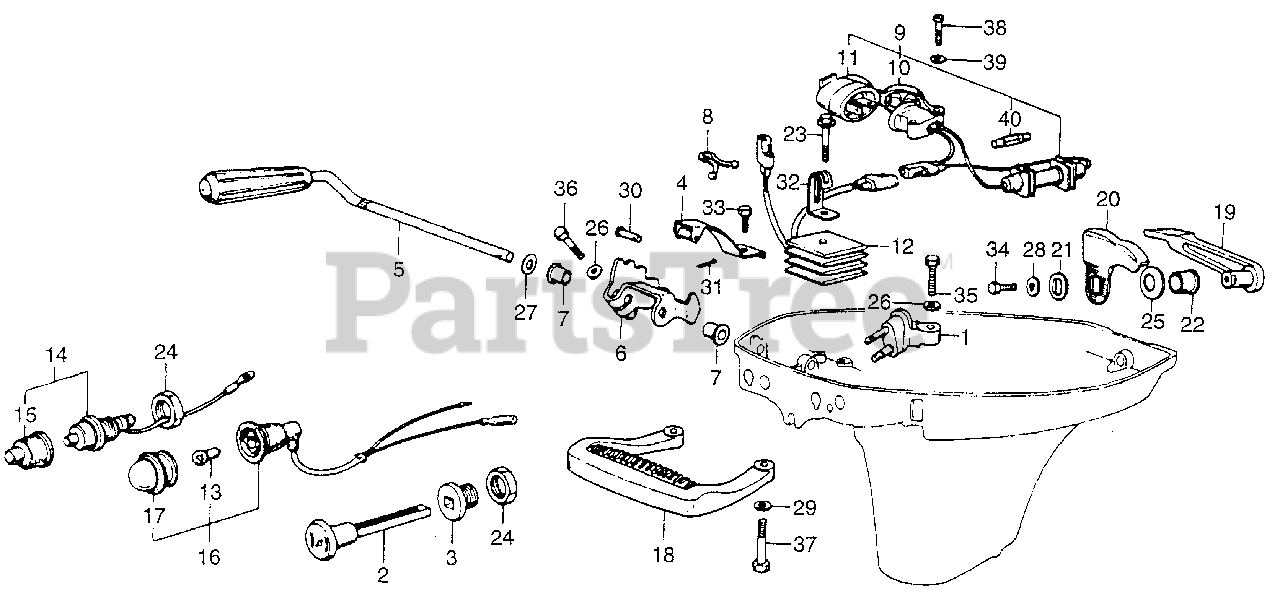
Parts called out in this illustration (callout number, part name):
1	CONNECTOR, FUEL *B9* (ATLANTIS BLUE) (NOT AVAILABLE)
2	KNOB, CHOKE
3	GUIDE, CHOKE KNOB
4	SPRING, CLICK
5	SHAFT, SHIFT
6	ARM, GEARSHIFT (NOT AVAILABLE)
7	BUSH, SHAFT
8	CLIP, PURSE LOCK (5MM)
9	RECEPTACLE ASSY., LAMP (NOT AVAILABLE)
10	RECEPTACLE (NOT AVAILABLE)
11	PLUG, RECEPTACLE
12	RECTIFIER ASSY.
13	BULB, DASH (12V3.4W) (IMASEN)
14	SWITCH, ENGINE
15	CAP, BUTTON (N/A: USE P/N 36100-921-000)
16	LAMP, INDICATOR (NOT AVAILABLE)
17	LENS (NOT AVAILABLE)
18	HANDLE, CARRYING *B9* (ATLANTIS BLUE)
19	LEVER, COVER LOCK *B9* (ATLANTIS BLUE) (NOT AVAILABLE)
20	HOOK, COVER LOCK
21	WASHER, COVER LOCK
22	BUSH, COVER LOCK
23	BOLT, FLANGE (6X35)
24	NUT, HEX. (16MM)
25	SPRING, LEVER
26	WASHER, PLAIN (6MM)
27	WASHER, PLAIN (10MM)
28	WASHER (6MM)
29	WASHER, PLAIN (8MM)
30	PIN (5X17)
31	PIN, COTTER (1.6MM)
32	CLIP, WIRE
33	BOLT, HEX. (6X12)
34	BOLT, HEX. (6X16)
35	BOLT, HEX. (6X20)
36	BOLT, HEX. (6X25)
37	BOLT, HEX. (8X32) (NOT AVAILABLE)
38	SCREW, PAN (5X22)
39	WASHER, PLAIN (5MM)
40	FUSE A (5A)
